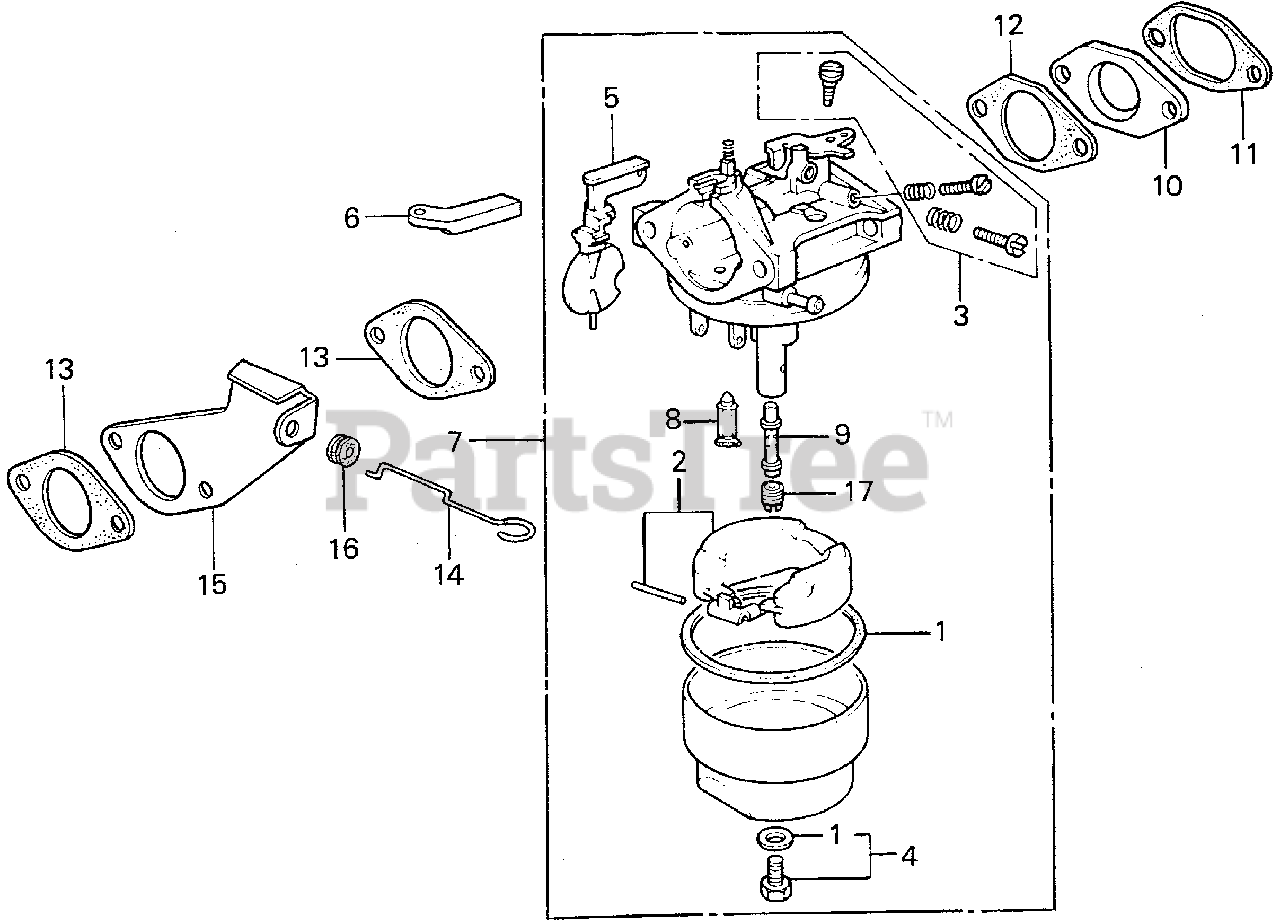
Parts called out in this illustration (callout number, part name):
1	GASKET SET
2	FLOAT SET
3	SCREW SET A
4	SCREW SET
5	CHOKE SET
6	ARM, CHOKE LEVER
7	CARBURETOR ASSY. (BB30A G)
7	CARBURETOR ASSY. (BB30C A)
7	CARBURETOR ASSY.
8	VALVE, FLOAT
9	NOZZLE, MAIN
10	INSULATOR, CARBURETOR
11	GASKET, INSULATOR
12	GASKET, CARBURETOR
13	GASKET, AIR CLEANER
14	ROD, CHOKE CONTROL
15	STAY, CHOKE CONTROL
16	GROMMET, CHOKE ROD
17	JET, MAIN (#65) Use from Engine SN BB30C A.
17	JET, MAIN (#68) Use from Engine SN BB30C A.
17	JET, MAIN (#70) Use from Engine SN BB30C A.
17	JET, MAIN (#72)
